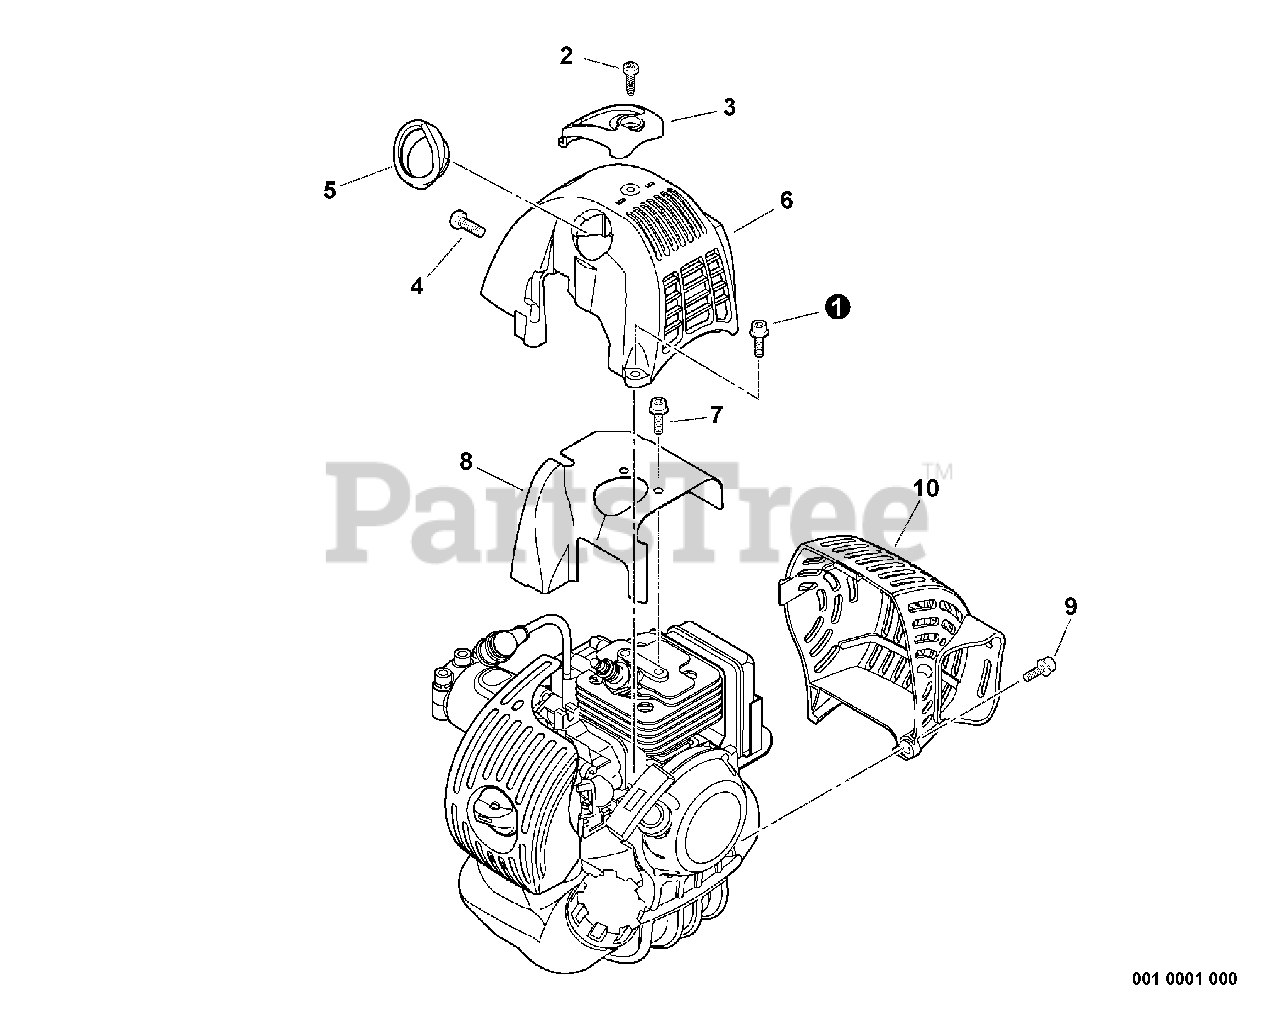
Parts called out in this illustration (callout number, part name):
1	BOLT 5×14
2	SCREW, TAPPING 5×16
3	GUARD, TOP
4	BOLT 5×12
5	GUARD, TOP - SPARK PLUG
6	COVER, ENGINE
7	BOLT 5×8
8	SHIELD, CYLINDER
9	BOLT 5×14
10	COVER, MUFFLER
